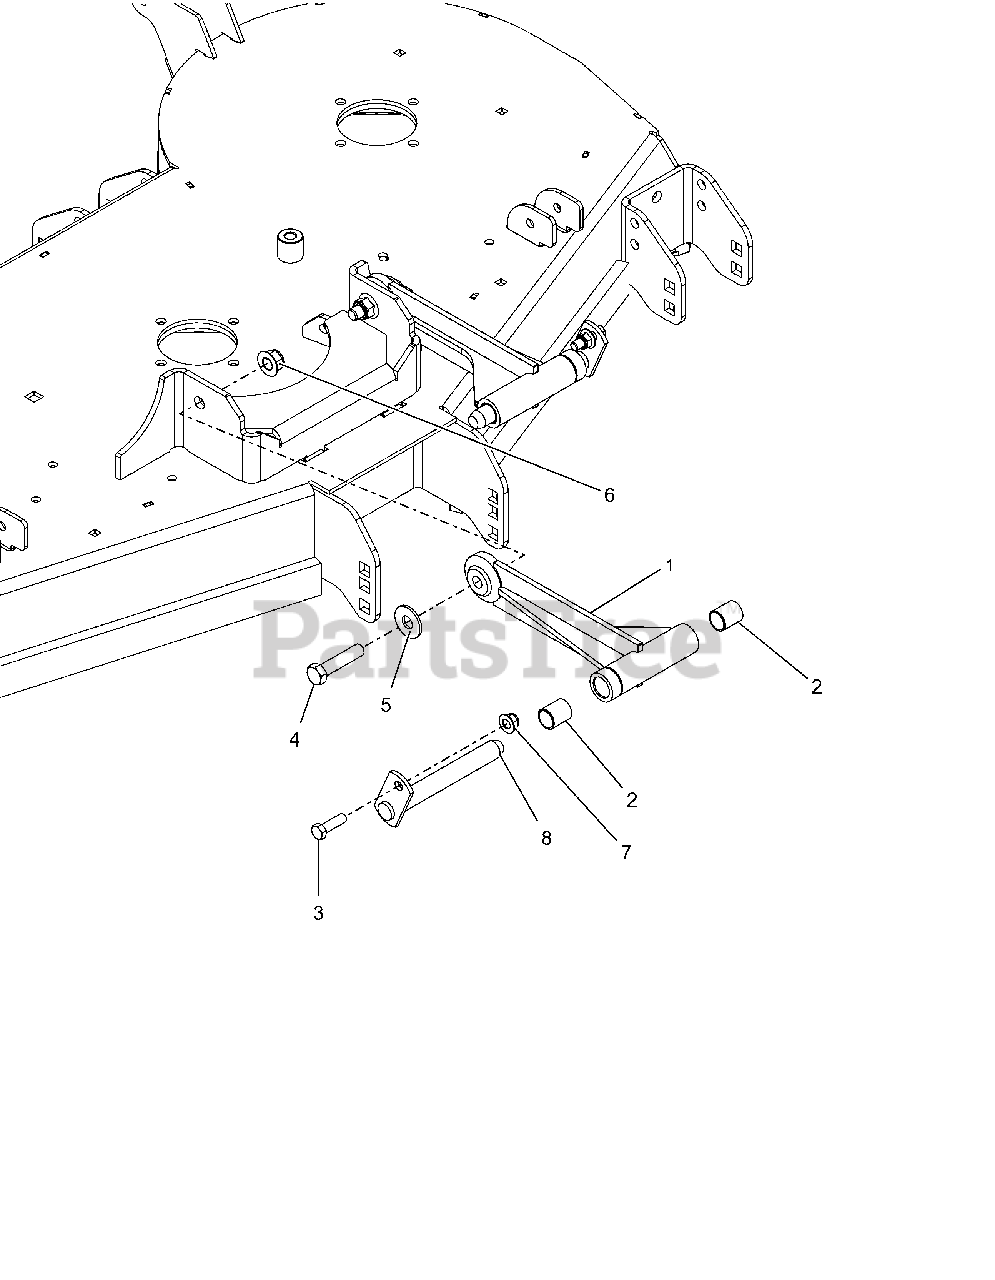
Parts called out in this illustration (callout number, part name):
1	WMT, DRAG LINK
2	BRG, .750 X .875 X 1.000
3	@BLT-HEX .38-16X1.25 GR5 YWZC
4	@BLT-HEX .50-13X2.25 GR5 YWZC
5	@WSHR-FL-STL.563X1.38X.109YWZC
6	@NUT-LK-NYL-FLG .50-13 YWZC
7	@NUT-LK-NYL-FLG .38-16 YWZC
8	WELDMENT, MOWER MTG. PIN
